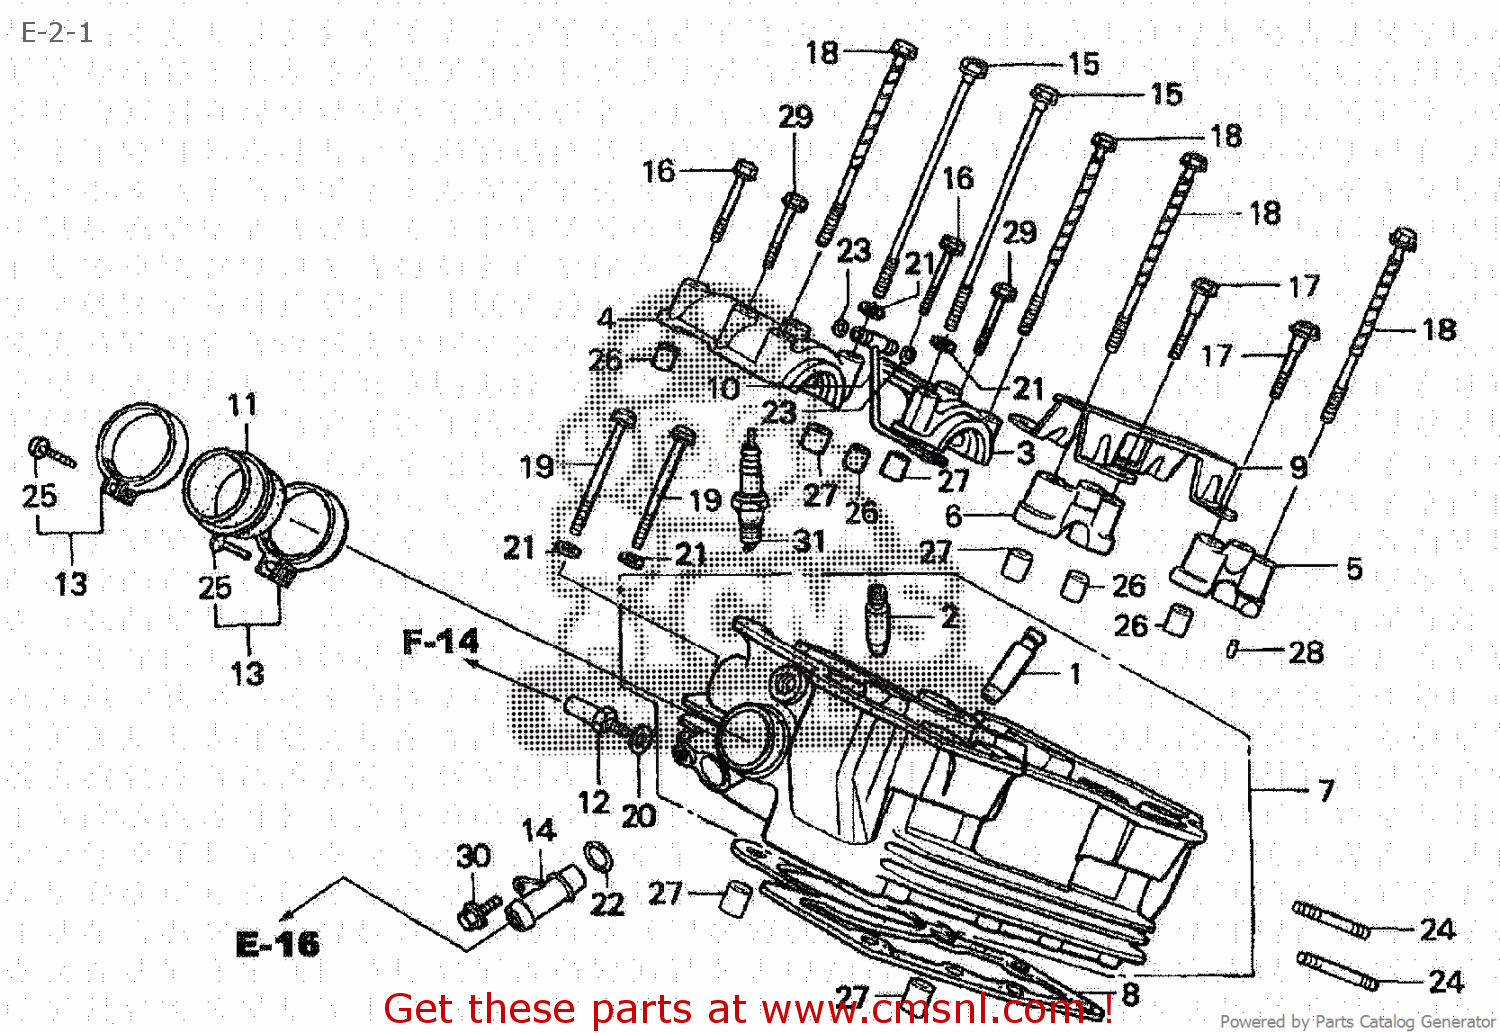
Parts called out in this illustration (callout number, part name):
1	GUIDE,VALVE(O.S)
2	GUIDE,IN.VALVE
3	HOLDER COMP A,CAM
4	HOLDER COMP B,CAM
5	HOLDER COMP C,CAM
6	HOLDER COMP D,CAM
7	HEAD COMP,REAR
8	GSKT,REAR HEAD (NAS)
9	GUIDE C,CAM CHAIN
10	PIPE OIL PATH
11	INSULATOR,CARB.
12	JOINT,BOOST
13	BAND,INSULATOR
14	PIPE C,WATER
15	BOLT,FLANGE,UBS,8
16	BOLT,UBS,6X40
17	BOLT,FLANGE,6X43
18	BOLT,UBS.,8X130
19	BOLT,UBS,8X80
20	WASHER 5MM
21	WASHER,8.5MM
22	O-RING 13X3
23	O-RING,5.6X1.9
24	BOLT,STUD 2,6X28
25	SCREW,CROSS 5X22
28	DOWEL,PIN,4X6.5
29	BOLT,FLANGE,
30	BOLT,FLANGE,SH,6X14
31	PLUG,SPARK(CR8EH9
